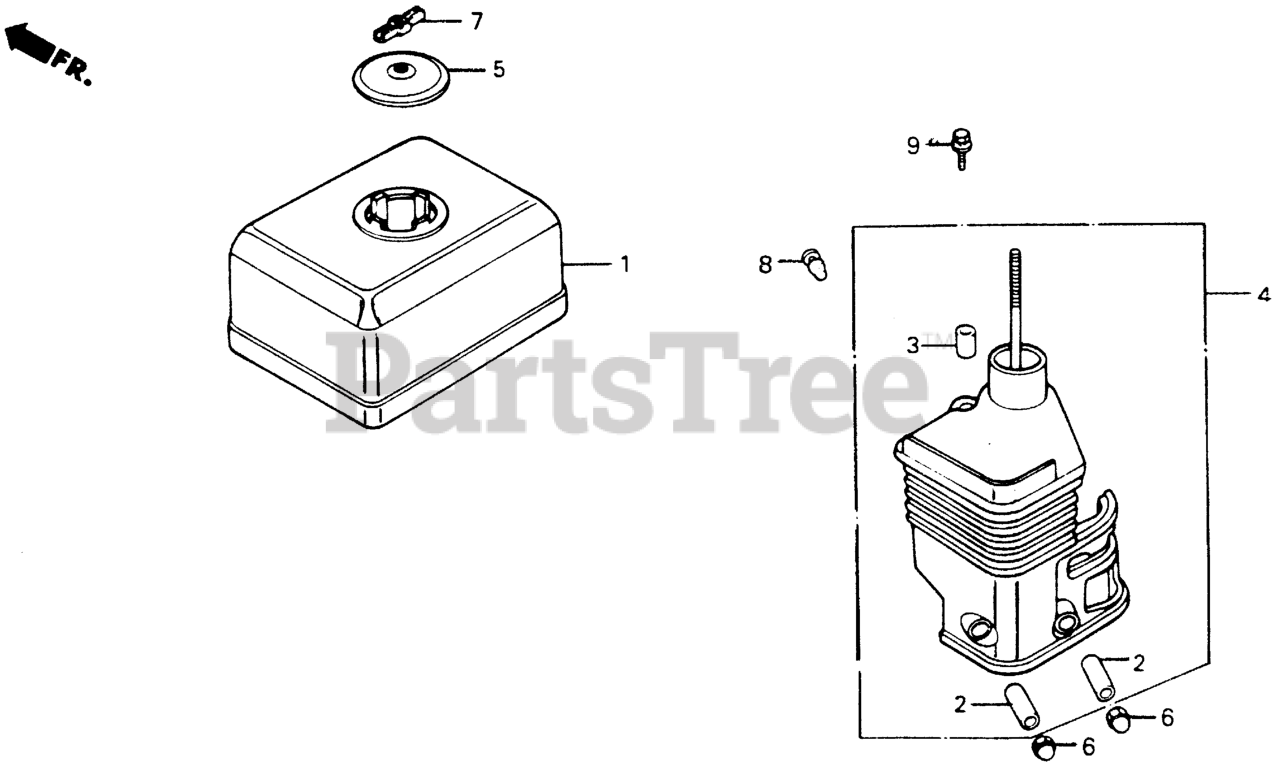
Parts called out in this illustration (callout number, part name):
1	COVER, AIR CLEANER (SEMI-DRY)
2	COLLAR, AIR CLEANER Use up to Engine SN 1786084.
3	COLLAR B, AIR CLEANER
4	ELBOW, AIR CLEANER Use from Engine SN 1220570 to 1786084.
5	CAP, CLEANER
6	NUT, CAP (6MM)
7	WINGNUT, AIR CLEANER COVER
9	BOLT-WASHER (6X20)
